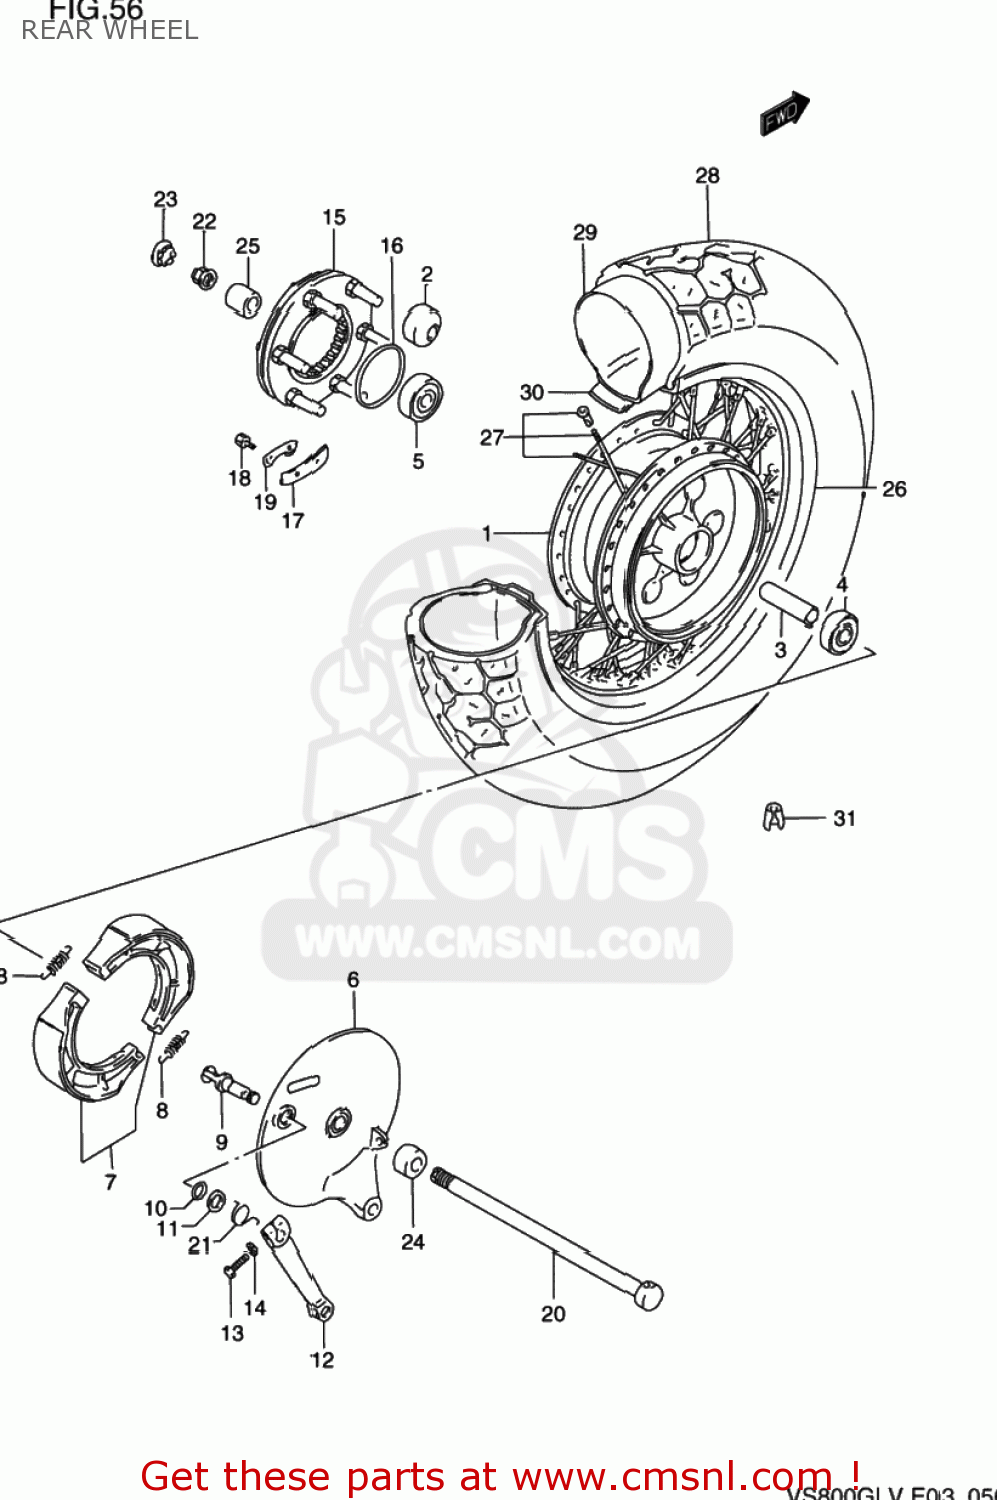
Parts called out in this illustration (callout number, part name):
1	HUB SET,RR
2	BUSH
3	SPACER(17.5X25X80)
4	BEARING
5	BEARING
6	PANEL,REAR BRAKE ANCHOR
7	SHOE SET,BRAKE (NAS)
8	SPRING,BRAKE SHOE
9	CAM,RR BRAKE
10	O RING(D:2.4,ID:14.8)
11	WASHER (15X24X1.6)
12	LEVER,RR BRAKE CAM
13	BOLT
14	WASHER,LOCK
15	JOINT ASSY,RR HUB DRIVEN
16	O RING(D:2.1,ID:65)
17	WASHER,THRUST(T:1.6)
18	BOLT(6X16)
19	WASHER
20	AXLE,RR
21	SPRING
22	NUT
23	CAP,RR AXLE,R
24	SPACER,REAR AXLE,RIGHT
25	SPACER,RR AXLE,L
26	RIM,REAR WHEEL (MT3.00X
27	SPOKE SET,RR WHEEL
28	TIRE,REAR 140/90-15M/C
29	TUBE ASSEMBLY,WHEEL,INNER
30	PROTECTOR,WHL INR TUBE
31	BALANCER,WHEEL
